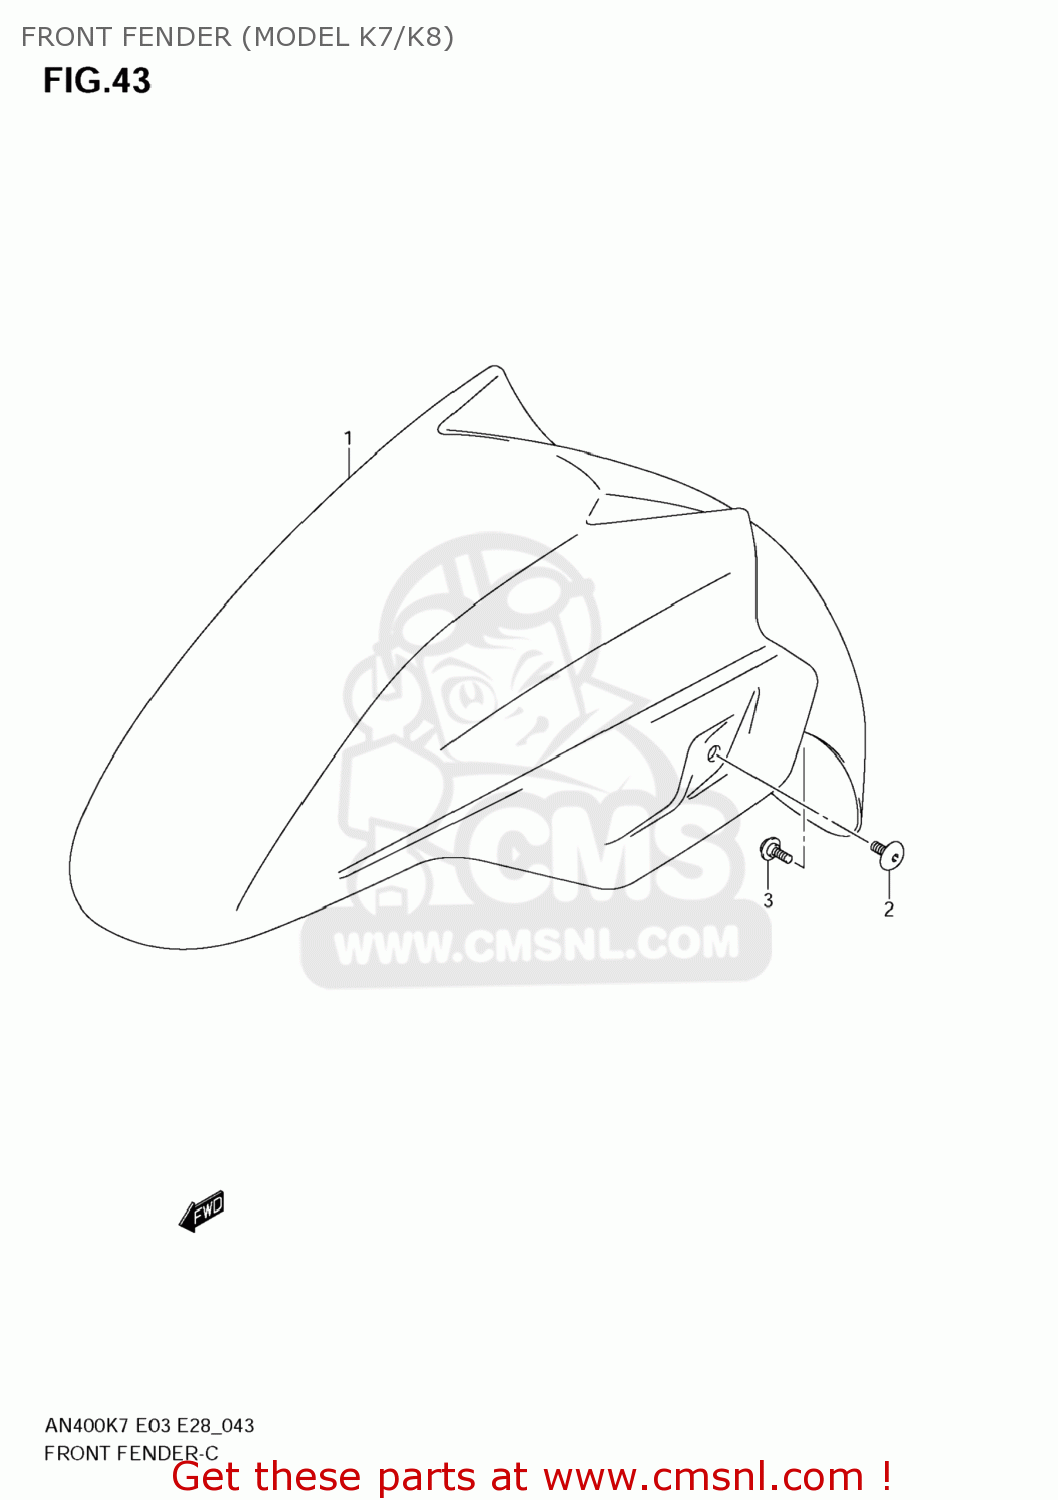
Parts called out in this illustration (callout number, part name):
1	FENDER,FR
2	SCREW(6X16)
3	BOLT 6X16.5
